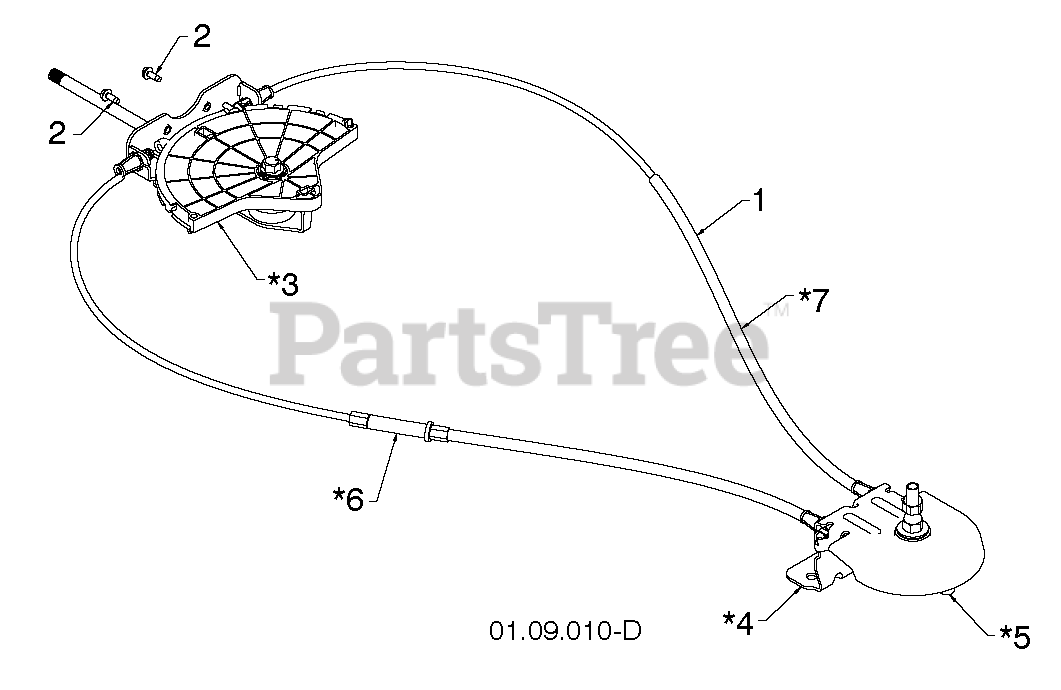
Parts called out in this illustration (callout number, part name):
1	LEVER/CABLE.ASM.ROTATOR
3	CHUTE.ROT.HEAD.SERVICE
4	BRACKET.ROTATOR.HEAD
5	SNOW.PIVOT.PULLY
6	SNOW.CBL.ASM.ADJ.SERVICE(74)
7	SNOW.CBL.ASM.SERVICE(428272)
